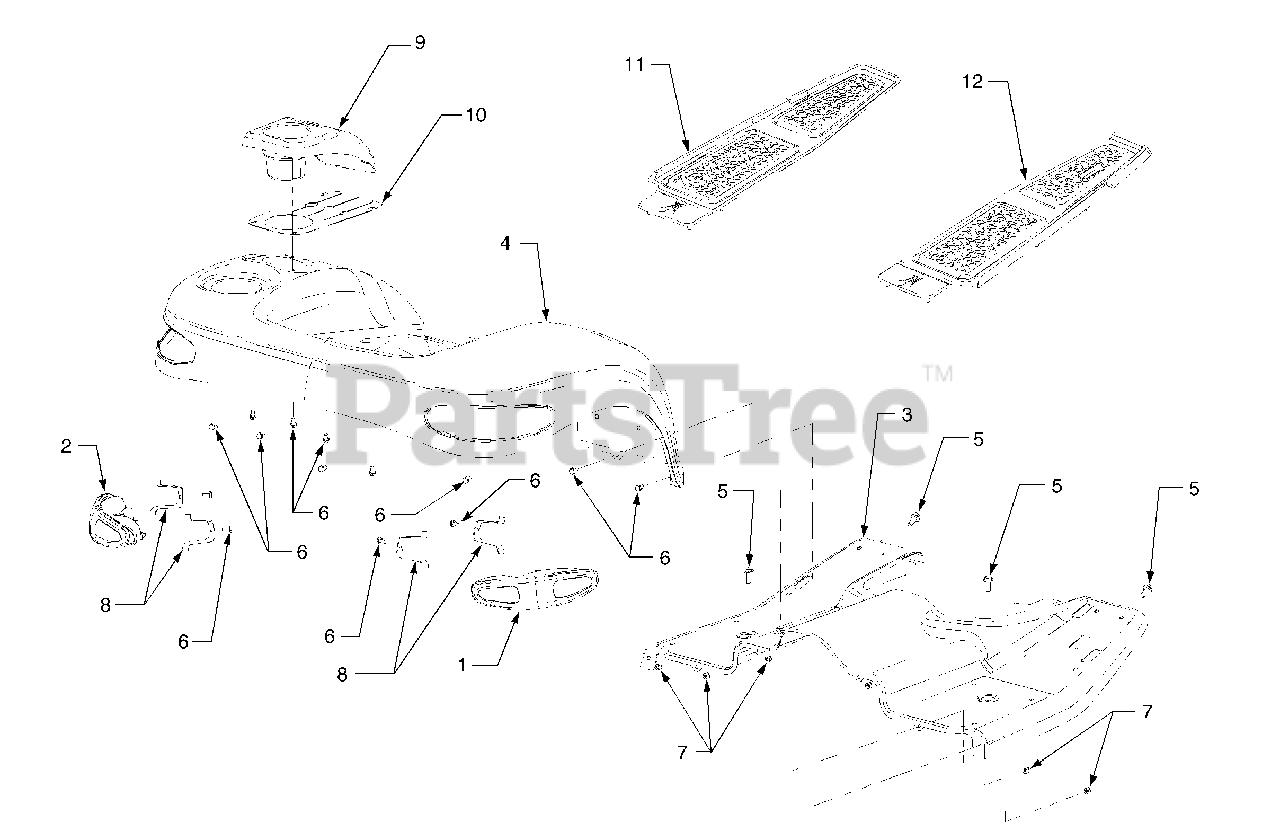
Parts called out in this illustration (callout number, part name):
1	Light Assembly, Rear RH
2	Light Assembly, Rear LH
3	Running Board
4	Fender
5	Screw, Hex Wash. Hd. Tapp 5/16-18 x 1.0
6	Screw, Hex Cap, 1/4-20 x .5 GR5
7	Nut, Hex Lock, 1/4-20
8	Clip, Tail Light
9	Cover, Lift Lever
10	Flap, Lift Lever
11	Pad. Floor LH
12	Pad. Floor RH
